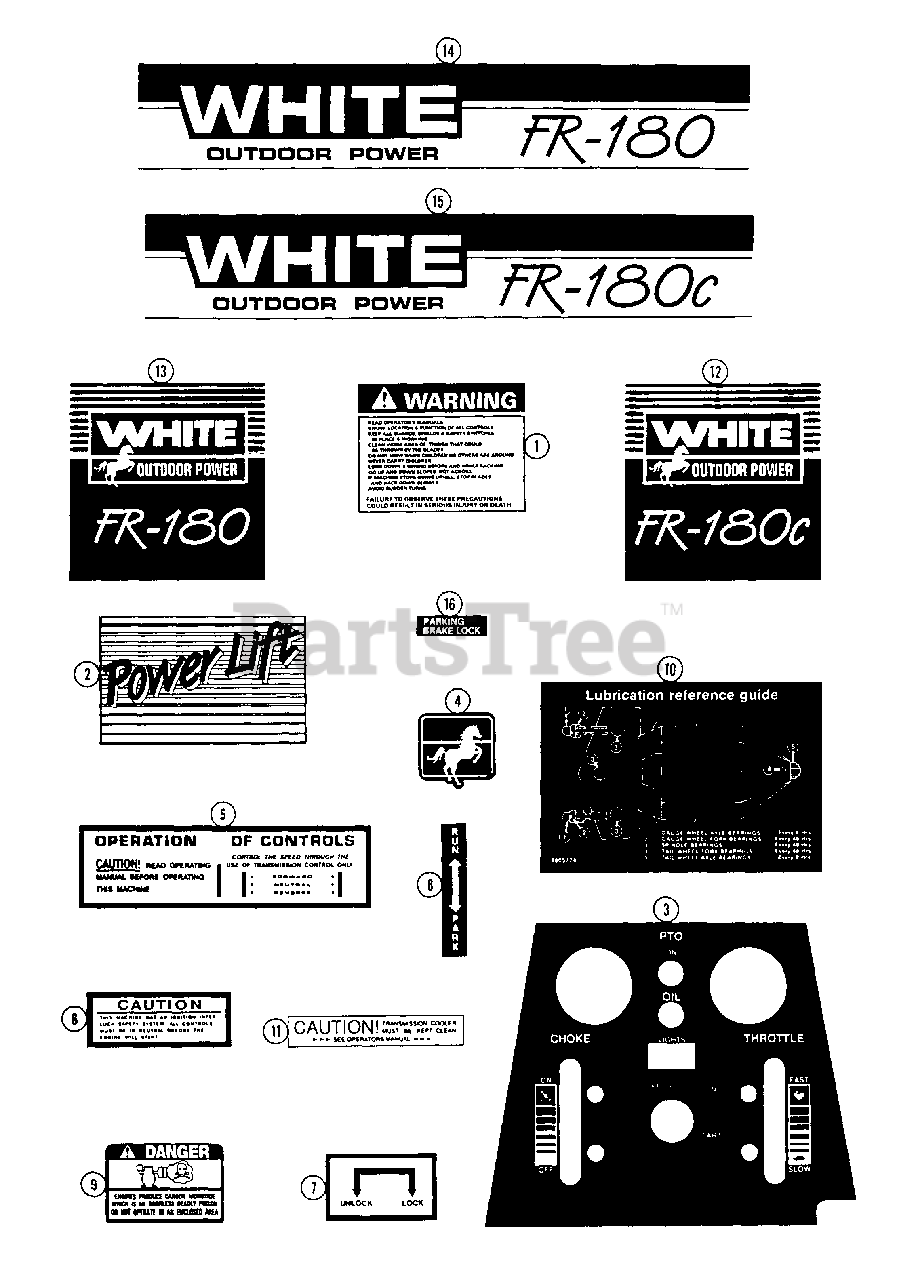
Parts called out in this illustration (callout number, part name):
1	DECAL - WARNING
2	DECAL - power lift
3	DECAL - instrument panel
4	MEDALLION - White "horse"
5	DECAL - operation
6	DECAL - caution interlock
7	DECAL - unlock/lock
8	DECAL - run/park
9	DECAL - danger carbon monoxide
10	DECAL - lubrication
11	DECAL - clean cooler
12	DECAL - front "FR180C"
13	DECAL - front "FR180"
14	DECAL - side R.H. "FR180"
14	DECAL - side L.H. "FR180"
15	DECAL - side R.H. "FR180C"
15	DECAL - side L.H. "FR180C"
16	DECAL - brake lock
